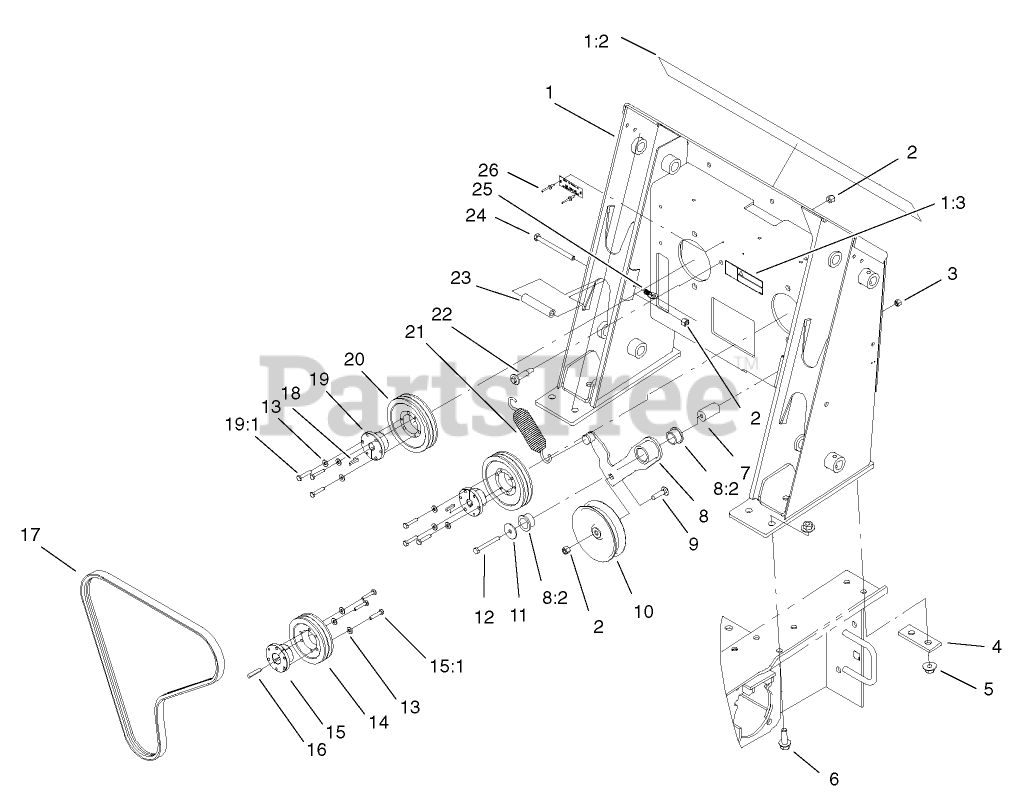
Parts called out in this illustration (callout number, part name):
1	LOADER TOWER ASM
1:2	DECAL-PANEL
1:3	DECAL-WARNING
2	NUT-LOCK, NI
3	NUT-LOCK, NI
4	PLATE-STIFFENER
5	NUT-LOCK, FLANGE
6	SCREW-HHF
7	SPACER-MOUNTING
8	IDLER ARM ASM
8:2	BUSHING-FLANGE
9	SCREW-CARR
10	PULLEY-IDLER
11	WASHER-FLAT
12	SCREW-HH
13	WASHER-FLAT
14	PULLEY
15	BUSHING
15:1	SCREW-HH
16	KEY-SQUARE
17	V-BELT
18	KEY-PUMP
19	BUSHING
19:1	SCREW-HH
20	SHEAVE
21	SPRING-EXTENSION
22	BOLT-WHEEL
23	TUBE-SPACER
24	SCREW-HH
25	LATCH ASM
26	RIVET-POP
